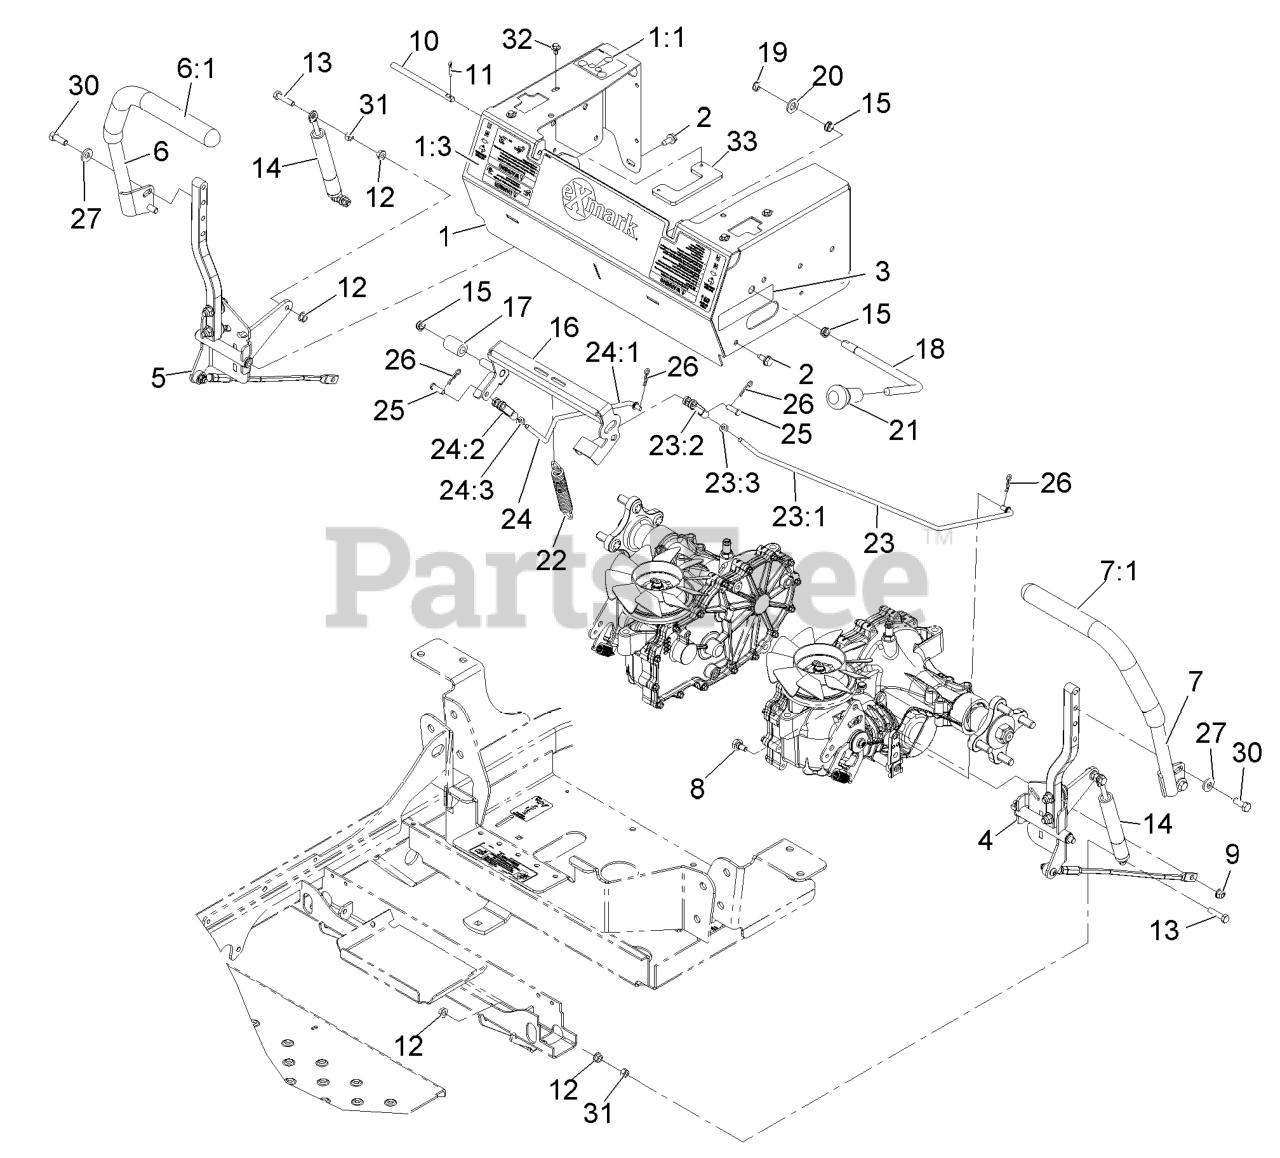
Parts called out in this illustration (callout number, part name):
1	ASM-MOT CTRL FRM W/DCL
1:1	DECAL-ROUTING, BELT
2	Screw-HWH 5/16-18 X 3/4 Tf
3	DECAL-E-SERIES
4	Motion Control Asm-Lh
5	Motion Control Asm-Rh
6	RH HANDLE ASM
7	LH HANDLE ASM
8	BOLT-SHOULDER,HFH
9	NUT-HF, NI
10	PIN-CONTROL PIVOT
11	PIN-COTTER
13	SCREW-HH
14	DAMPER-MOTION CONTROL
15	BUSHING,SNAP
16	ASM-BRAKE CENTER ARM
18	HANDLE,BRAKE
19	RING-RETAINING, EXTERNAL
20	WASHER-FLAT
22	SPRING-DECK, ENGAGEMENT
23	BRAKE LINKAGE ASM-LH
23:1	LINKAGE,BRAKE LH
23:2	YOKE-ADJUSTABLE
23:3	NUT-JAM
24	BRAKE LINKAGE ASM-RH
24:1	LINKAGE-BRAKE, RH
24:2	YOKE-ADJUSTABLE
24:3	NUT-JAM
25	PIN-CLEVIS
26	PIN-COTTER
27	WASHER-BELLEVILLE
30	SCREW-HH
31	NUT-HEX
32	SCREW-HHFTF
33	STOP-MOTION CONTROL
